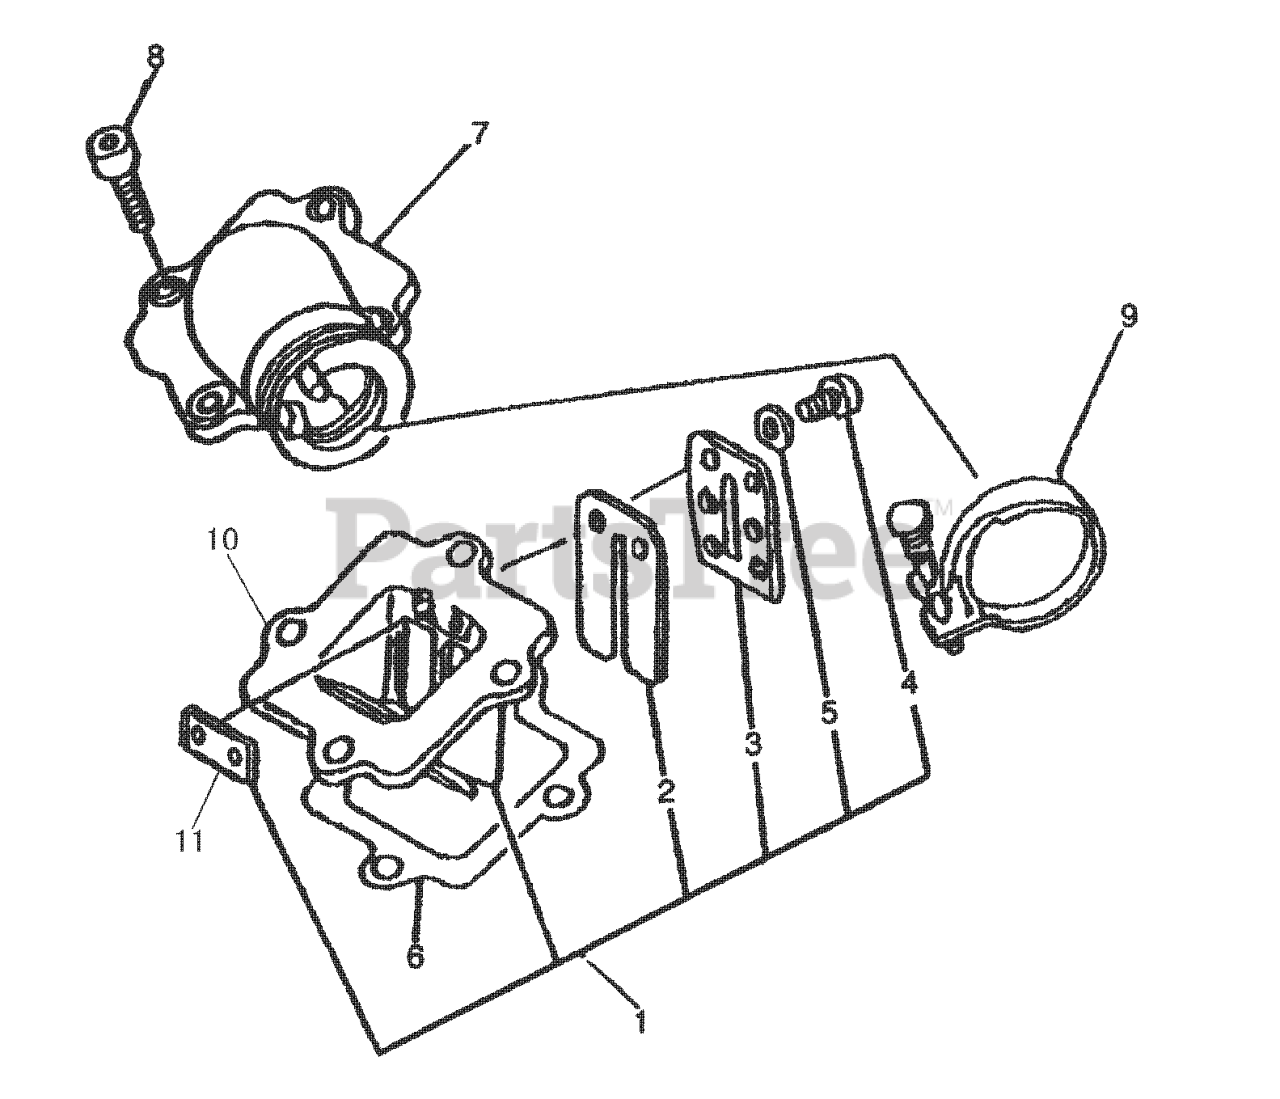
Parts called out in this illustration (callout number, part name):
1	REED VALVE ASSY
2	REED VALVE
3	REED VALVE STOPPER
6	VALVE SEAT GASKET
7	PIPE, INTAKE
9	CLAMP, HOSE
10	VALVE SEAT
11	REED VALVE GASKET
